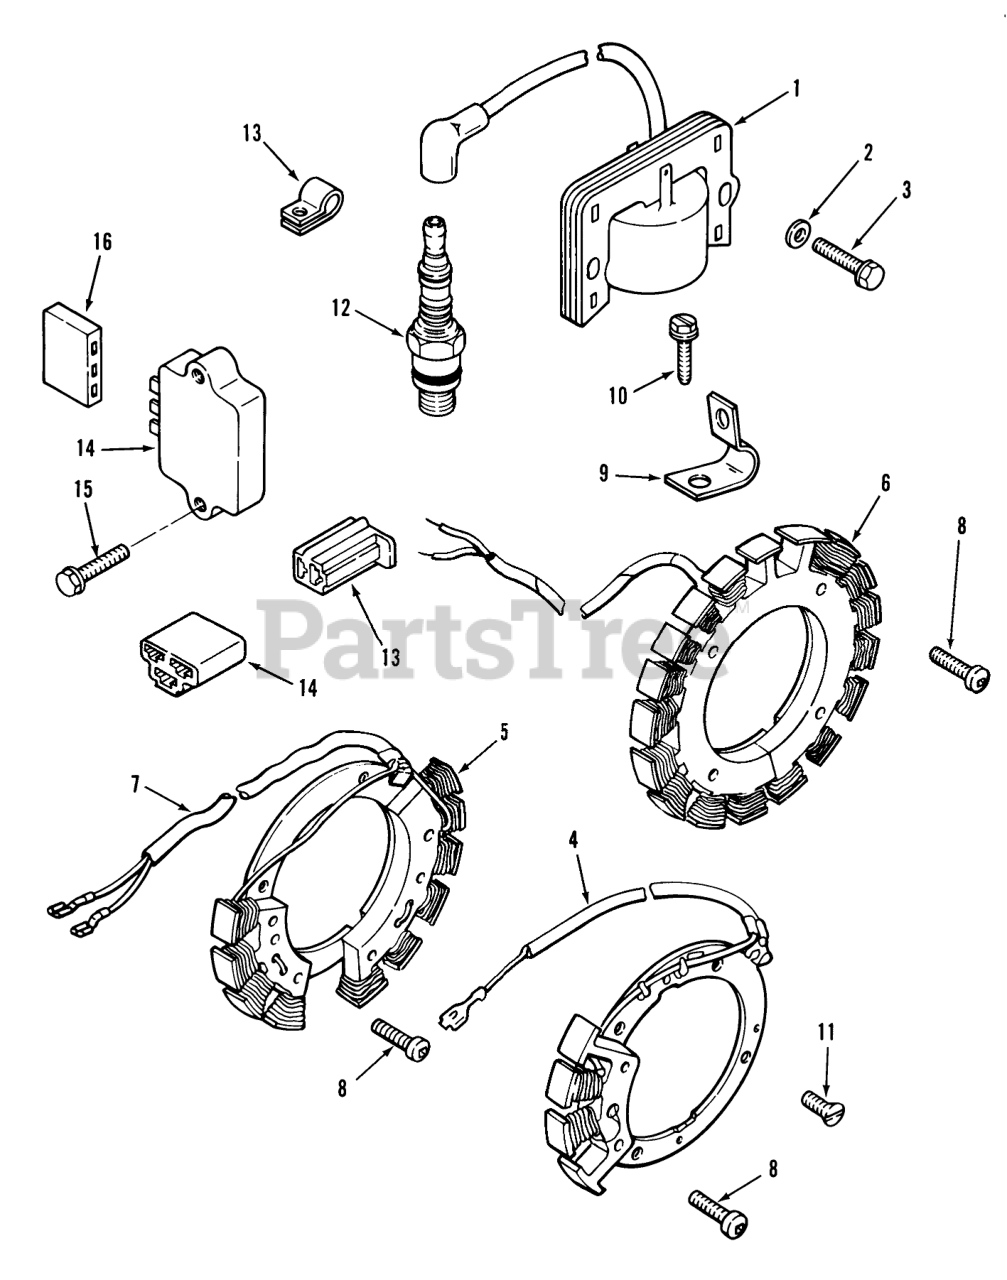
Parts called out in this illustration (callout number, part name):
1	Ignition Module 308 Only
2	Washer
3	Screw
4	Stator 1.5 amp w/70W light coil 308 Only
5	Stator Assy 3 amp (includes 7) 310 Only
6	Stator Kit 15 amp (includes 8) 312, 414, 416 Only
7	Diode Kit 310 Only
8	Pozidriv. Pan Hd. Screw #10-24 x 3/4
9	Clip-Hi-Tension
10	Hex. Wash. Hd. Screw 8-32 x 3/8
11	Sltd F.H. Screw 10-24 x 3/8 308
12	Spark Plug 308 Only
13	Clip-Hi-Tension
14	Regulator-Rectifier
15	Screw
16	Connector
